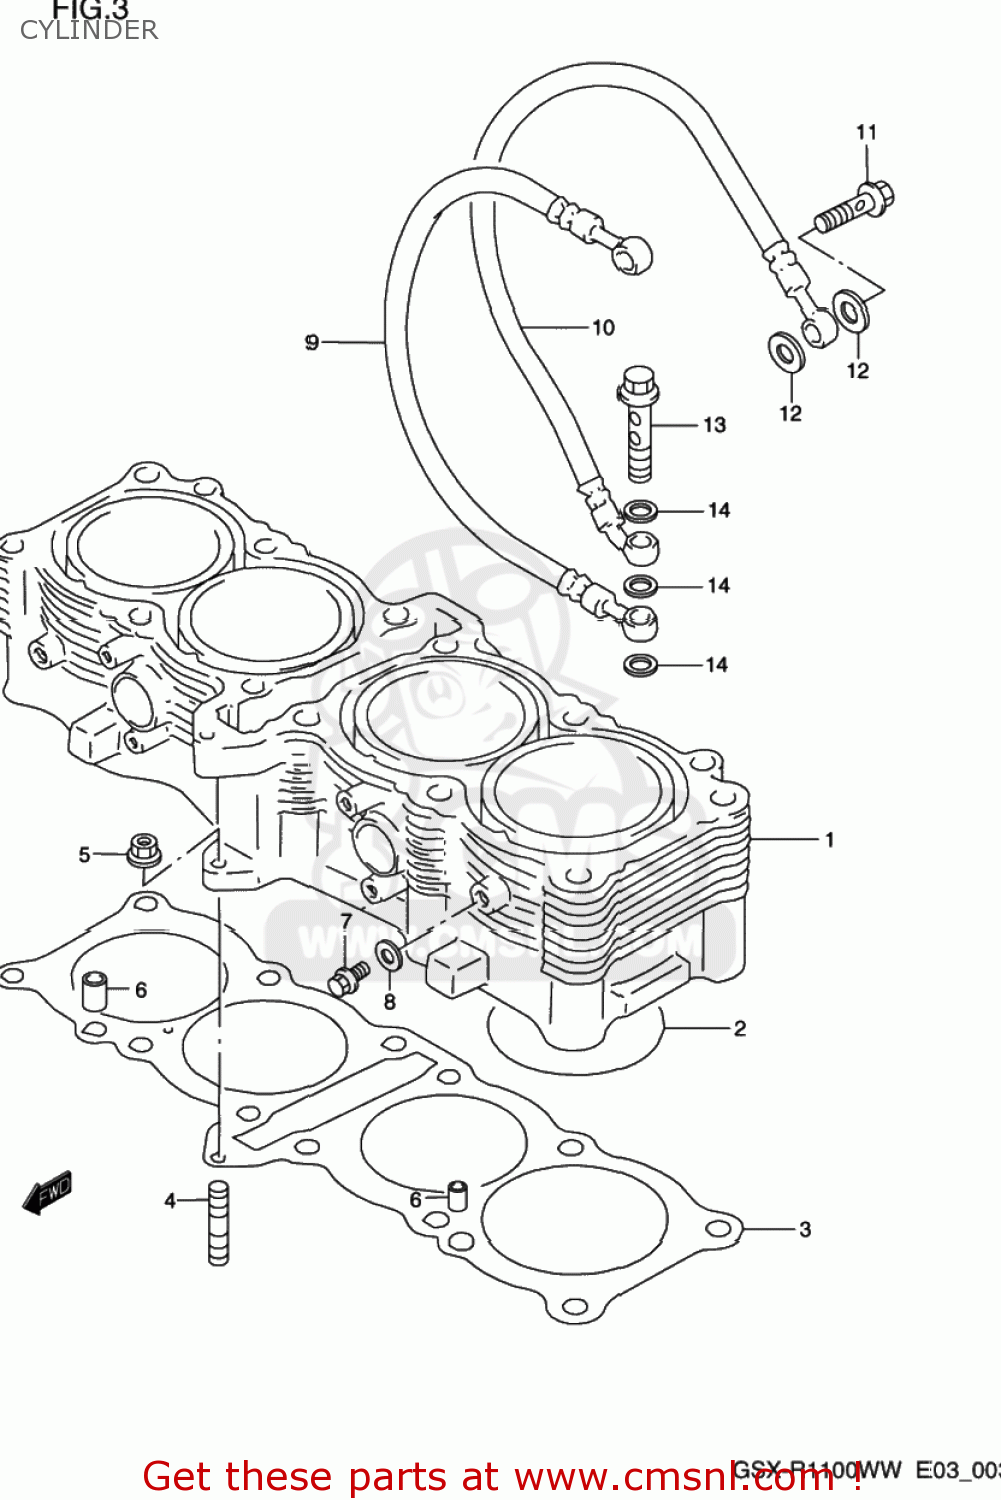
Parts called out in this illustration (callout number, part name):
1	CYLINDER
2	O RING(D:1.9,ID:79.5)
3	GASKET,CYLINDER
4	STUD,M6X1X32
5	NUT
6	PIN
7	BOLT,DRAIN
8	GASKET 8.2X14X1 (NAS)
9	HOSE,OIL
10	HOSE,OIL
11	BOLT,OIL PIPE UNION,NO
12	GASKET (NAS)
13	BOLT,OIL PIPE UNION,NO
14	WASHER(10X15X1.5)
